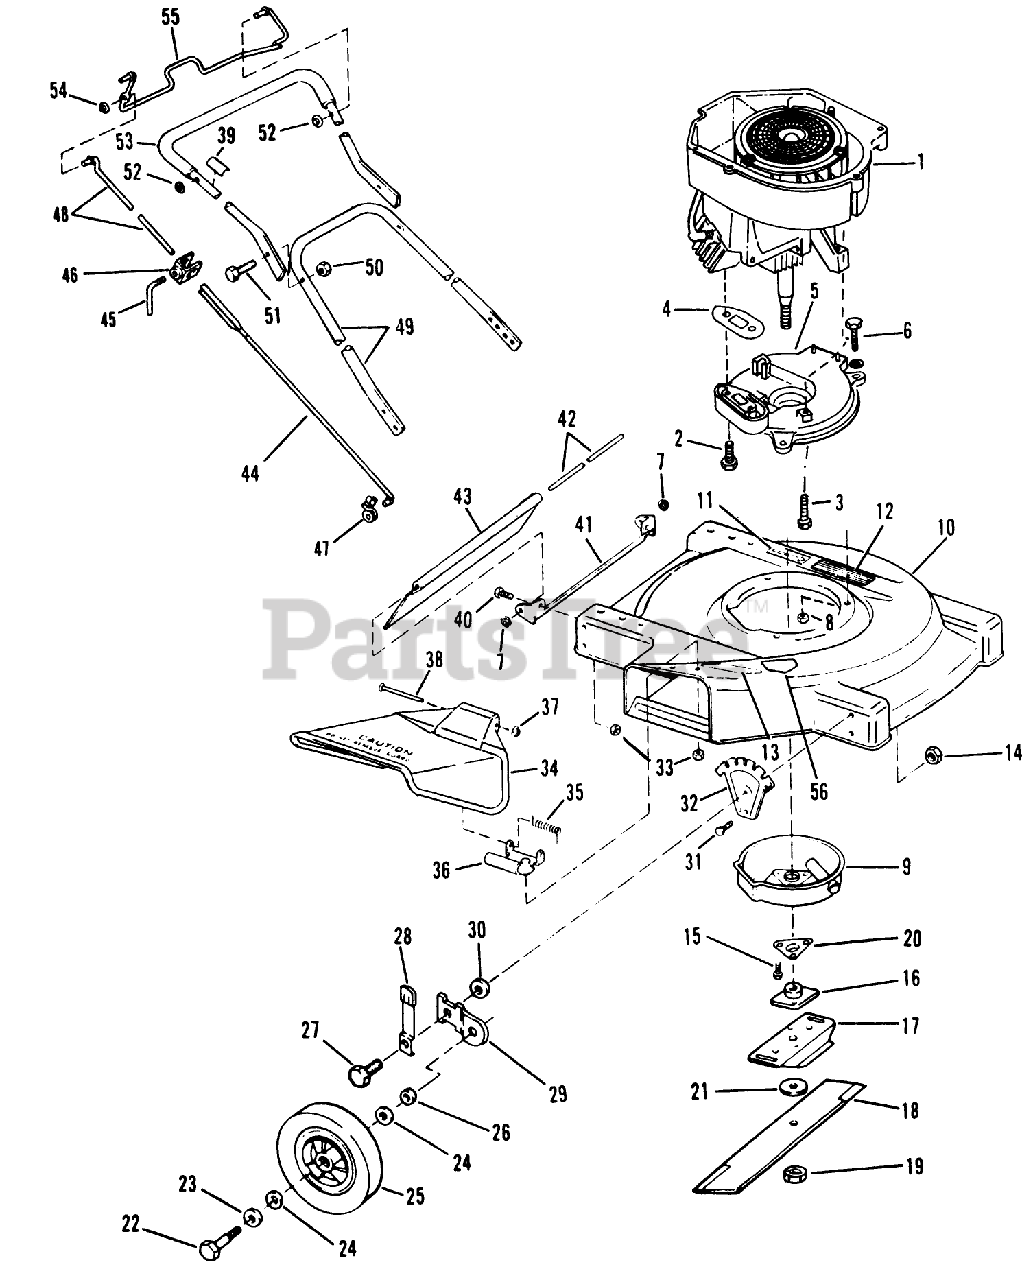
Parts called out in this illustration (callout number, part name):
2	SCREW V
3	Screw-Muffler Plate to Cylinder
6	SCREW
8	NUT-LOCK F
12	PAD FOOT
14	LOCKNUT
15	SCREW
16	PLATE AND COLLAR ASM
18	BLADE EURO WHIRL
19	NUT-BLADE
20	SUPPORT F
21	WASHER
22	BOLT WHEEL
23	SPACER
24	WASHER
26	WASHER WROUGHT
27	BOLT
28	KNOB&SPRING FORMCO
30	WASHER
33	LOCKNUT E
34	CHUTE DEFLECTOR AY
36	HINGE & SCREW ATA
38	PIN
41	BRACKET (12)
43	TRAILING SHIELD
47	CLIP
50	LOCKNUT E
51	SCREW - USE 137-3042
